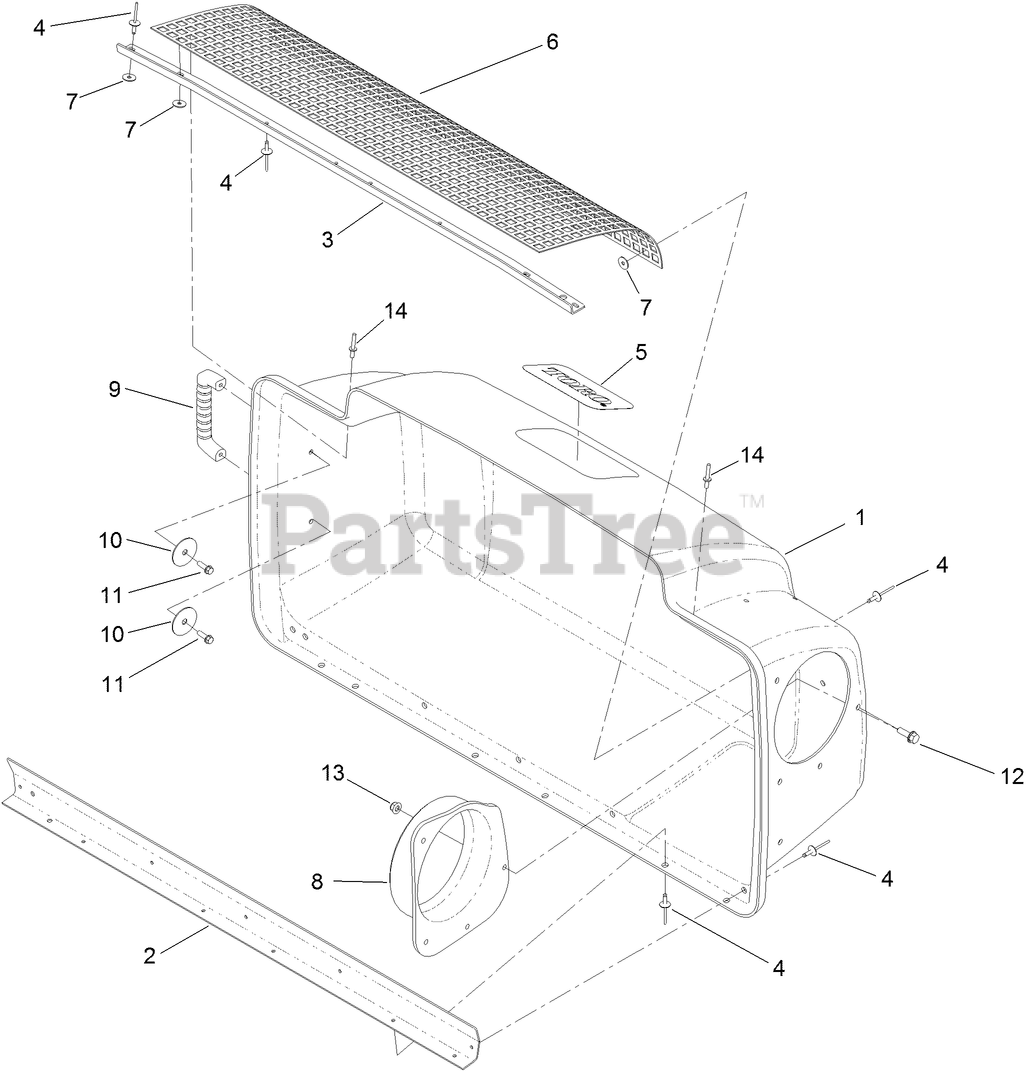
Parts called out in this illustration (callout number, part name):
1	TOP-BAGGER
2	STIFFENER-BAGGER, TOP
3	SUPPORT, SCREEN
4	RIVET-BLIND
5	DECAL
6	SCREEN-BAGGER
7	WASHER-FLAT
8	ADAPTER-INLET, HOOD
9	HANDLE-DOOR
10	WASHER
11	SCREW-HWH
12	SCREW-HHF
13	NUT-HF, NI
14	RIVET-POP
